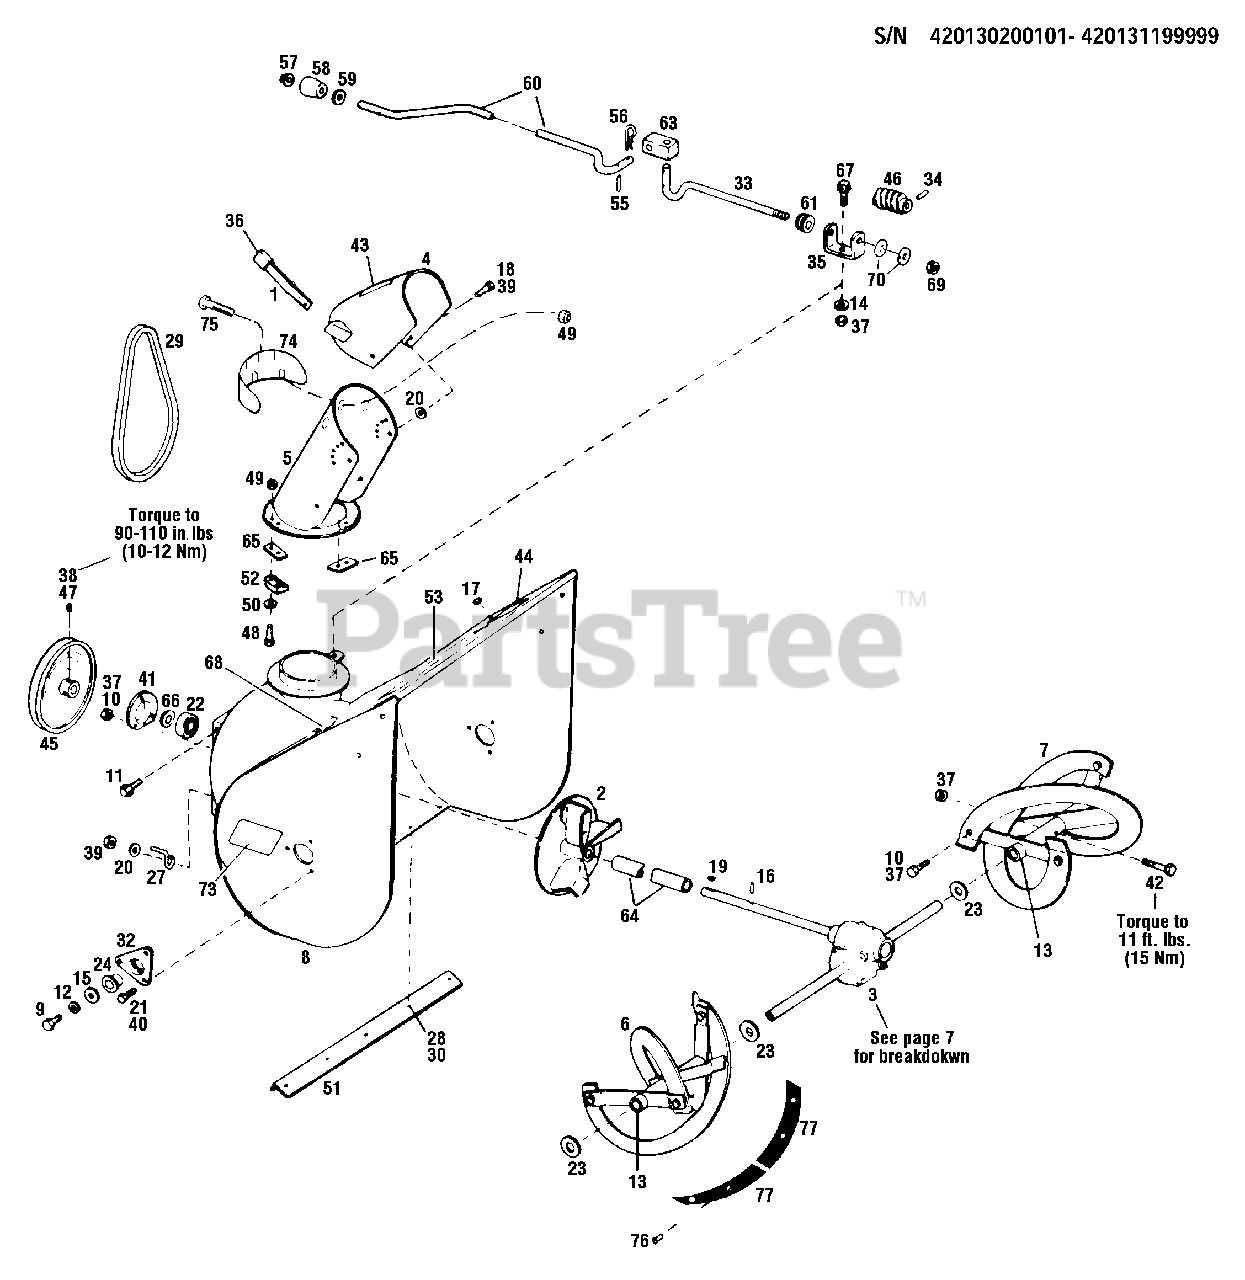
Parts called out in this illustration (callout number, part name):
1	Adjusting Lever
2	Impeller
3	Gear Case Assembly
4	Cap
6	Auger Blade, RH
7	Auger Blade, LH
8	Housing
9	Boat, 1/2-13 x 3/4
10	Bolt 5/16-18 x 5/8
11	Flange Lock Bolt 5/16-18 x 3/4
12	Lockwasher, 1/2
13	Auger Support
14	Flat Washer, 5/16
15	Flat Washer, 1/2
16	Roll Pin, 1/4 x 1-1/4
17	Button Plug
18	Bolt, 3/8-16 x 3/4
19	Hi-Pro Key, 3/16 x 3/4
20	Flat Washer, 3/8
21	Bolt, 1/4-20 x 5/8
22	Ball Bearing
23	Special Washer, 1-1/64 I.D.
24	Flange Bushing
27	Belt Guide
28	Flange Locknut 5/16-18
29	V-Belt, 36"
30	Carriage Bolt, 5/16-18 x 1/2
32	Support Bearing
33	Chute Control Shaft
34	Drive Pin, 3/32 x 3/4
35	Gear Support
37	Toplock Nut, 5/16-18
38	Set Screw, 5/16-18 x 5/8
39	TOplock Nut, 3/8-16
40	Toplock Nut, 1/4-20
41	Bearing Retainer
42	Special Shear Bolt, 5/16-18
43	Chute Danger Decal
44	Housing Danger Decal
45	Auger Drive Pulley
46	Worm Gear, 6 Thread, LH
47	Loctite 1242, .02 oz. Tube
48	Sems Screw, #10-24 x 7/8
49	Toplock Nut, 10-24
50	Flat Washer, #10
51	Scraper Blade
52	Hold-down Clip
53	Logo Decal
55	Drive Pin, 1/8 x 3/4
57	Push-on Cap
58	Knob
59	Flat Washer, 3/8
60	Chute Control Crank
61	Nylon Bushing
63	Swivel Block
64	Sleeve
66	Shim Washer, 1-1/4 I.D. x .020
67	Flange Bolt 5/16-18 x 3/4
68	American Legend Decal
69	Top Lock Range Nut, 3/8-16
70	Nylon Washer
72	Drift Slicer Kit
73	Housing Side Decal
74	Chute Deflector
75	Truss Head Bolt, 10-24
76	Pop Rivet
77	Auger Pad Ka
